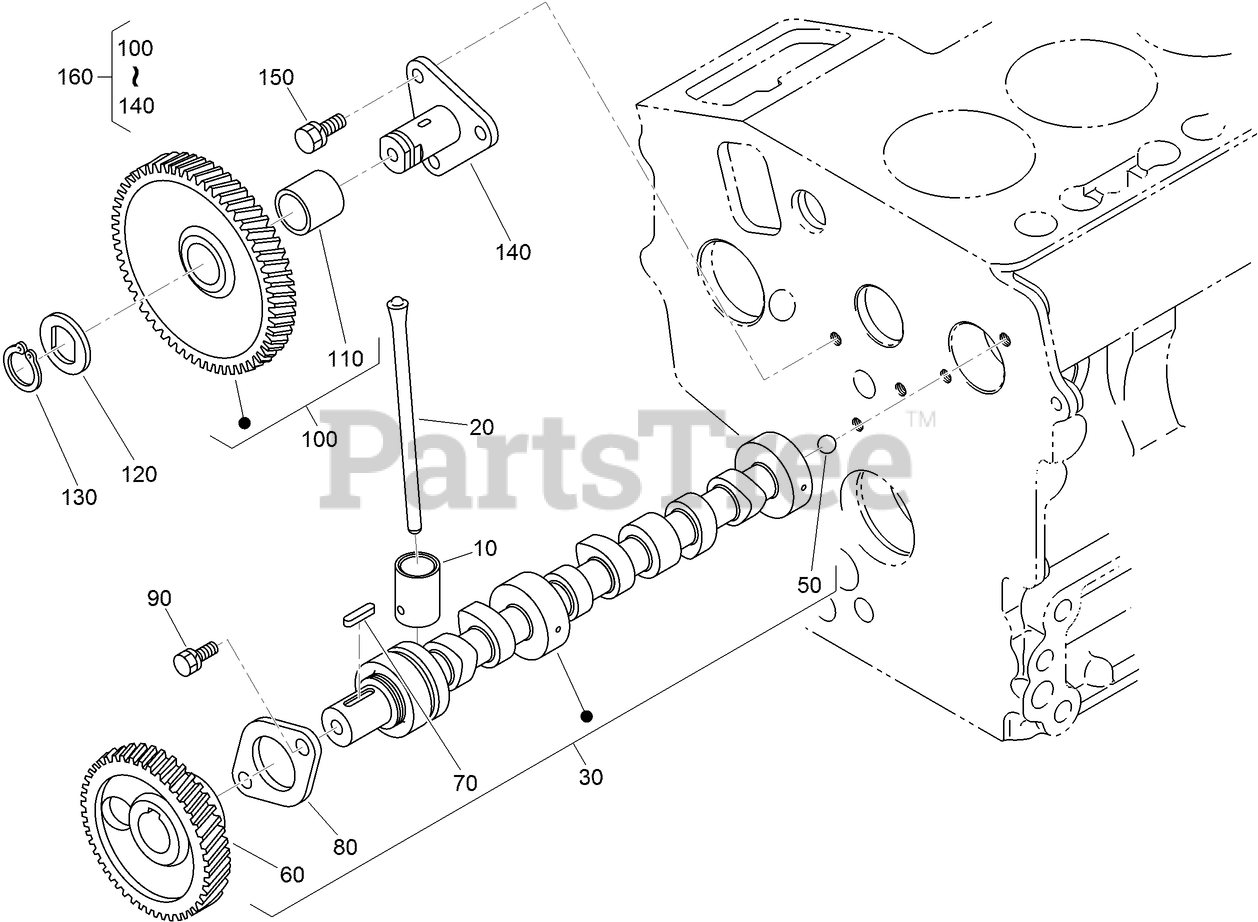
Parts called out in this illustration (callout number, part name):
10	TAPPET
20	ROD-PUSH
30	CAMSHAFT ASM
60	GEAR-CAM
70	KEY-FEATHER
80	STOPPER-CAMSHAFT
100	IDLE GEAR ASM
110	BUSHING
120	COLLAR-GEAR, IDLE
130	RING-SNAP
140	SHAFT-GEAR, IDLE
150	BOLT-FLANGE
160	IDLE GEAR ASM
